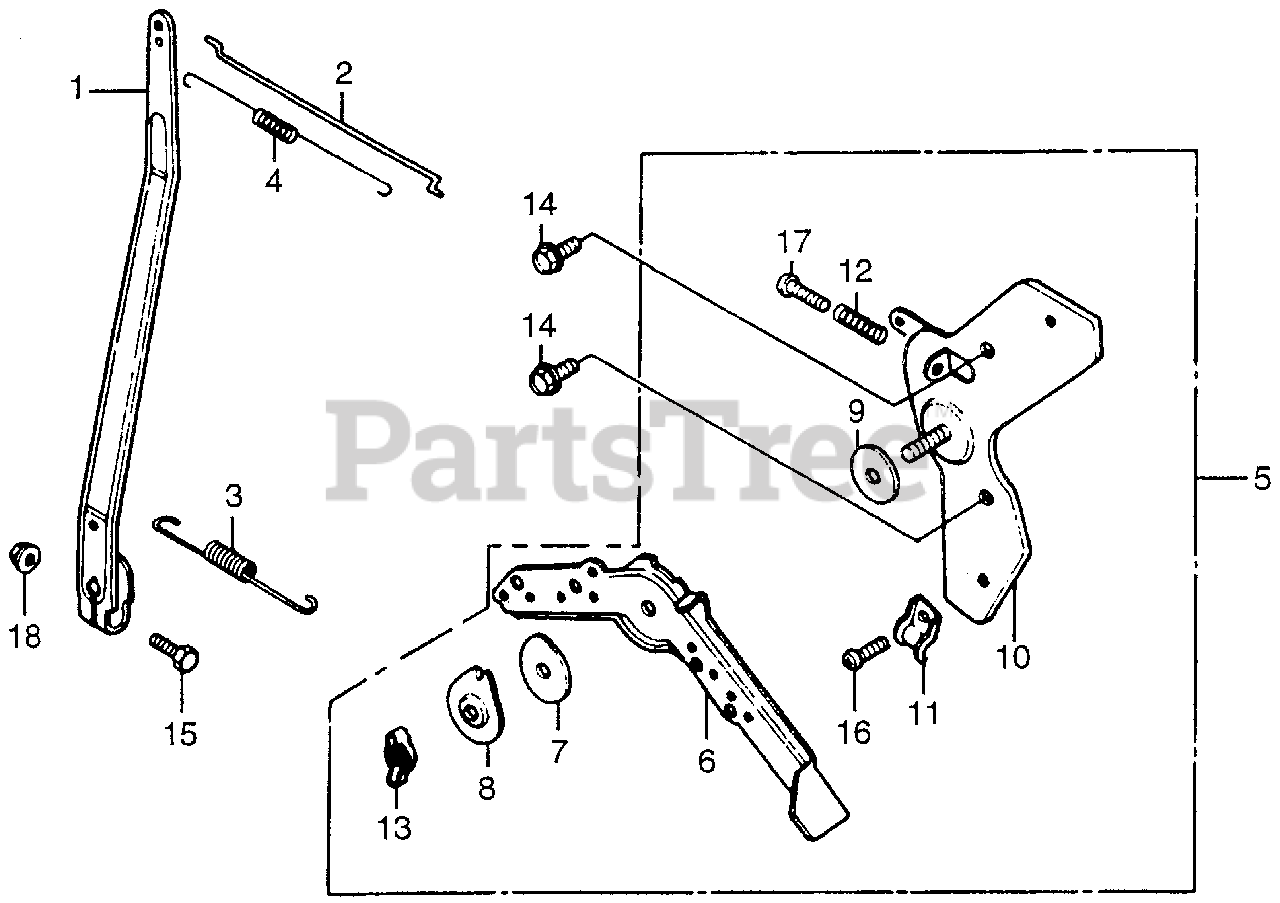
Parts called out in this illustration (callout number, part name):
1	ARM, GOVERNOR
2	ROD, GOVERNOR
3	SPRING, GOVERNOR
4	SPRING, THROTTLE RETURN
5	CONTROL ASSY.
6	LEVER, CONTROL
7	SPRING, LEVER
8	WASHER, CONTROL LEVER
9	SPACER, CONTROL LEVER
10	BASE, CONTROL LEVER
11	HOLDER, CONTROL CABLE
12	SPRING, CONTROL ADJUSTING
13	WINGNUT (6MM)
14	BOLT, FLANGE (6X12) (CT200)
15	BOLT, HEX. (6X20)
16	SCREW, PAN (5X10)
17	SCREW, PAN (5X22)
18	NUT, FLANGE (6MM)
